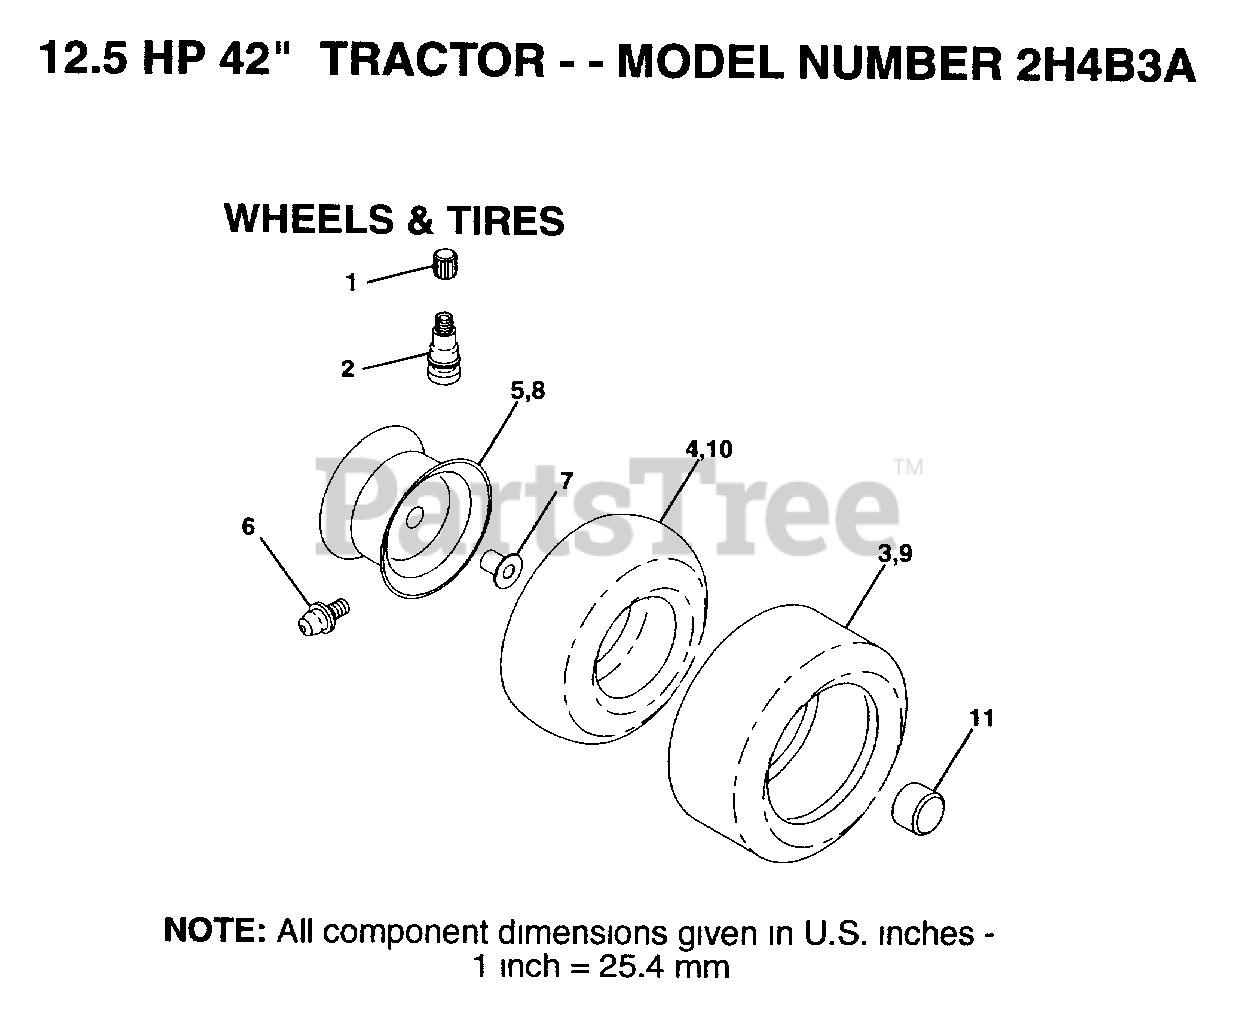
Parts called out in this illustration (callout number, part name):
1	VALVE CAP
2	VALVE STEM LT
4	TUBE.5.3/4.5/6
6	FITTING LT
7	"FLANGE, BEARING"
10	TUBE.18X9.5-8
11	HUB CAP
